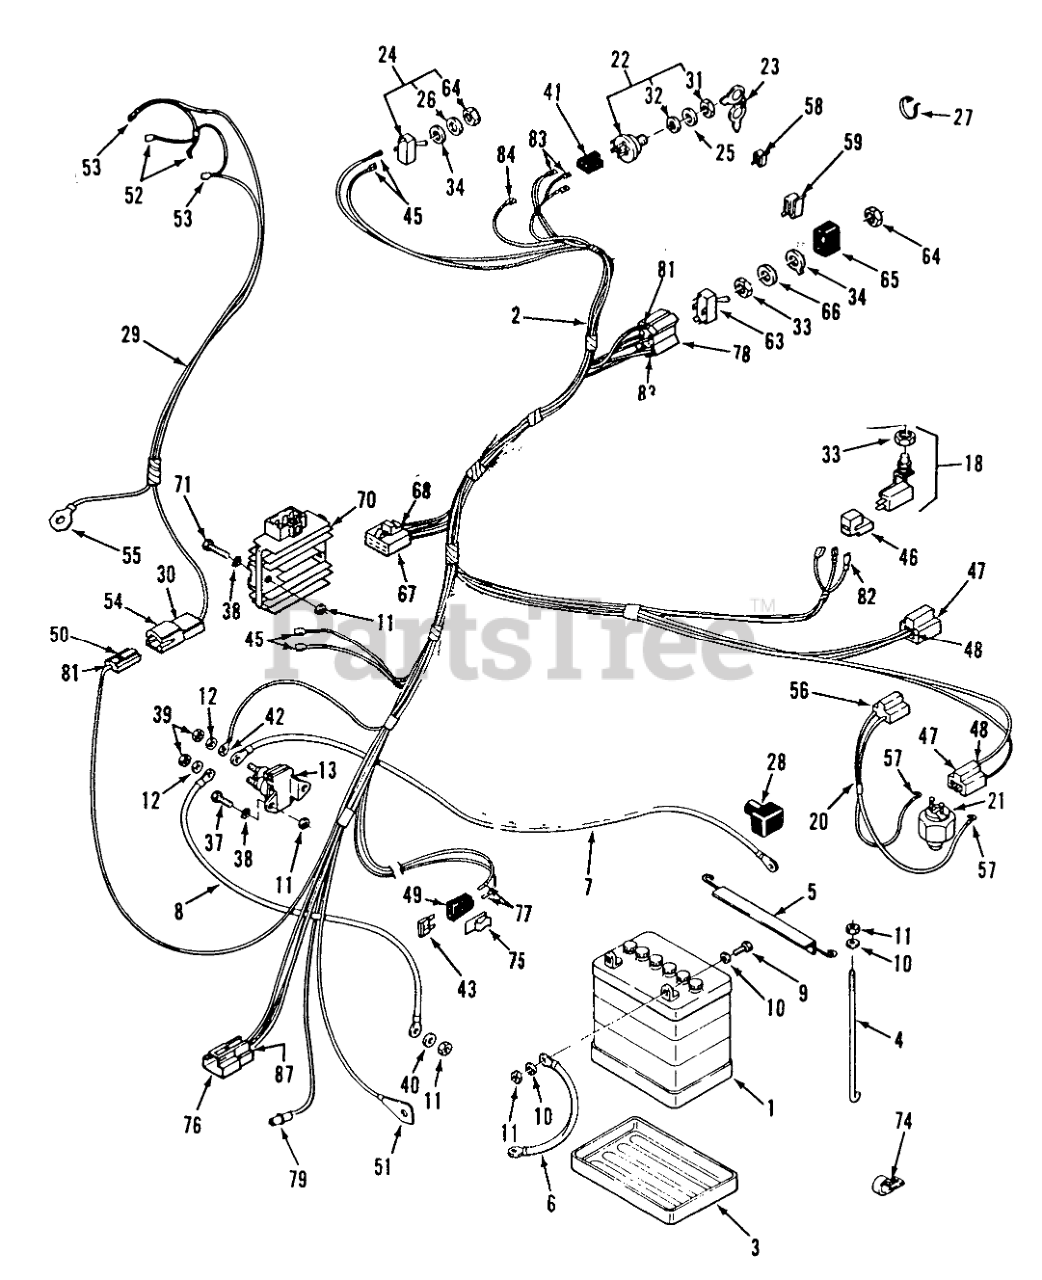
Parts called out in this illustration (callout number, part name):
1	Battery
2	MAIN HARN & WIR DIAG
3	TRAY BATTERY
5	HOLDDOWN-BATTERY
6	WIRE -BLACK
7	WIRE - 14" BLACK
8	ASSY WIRE
9	Bolt
11	Nut
12	Washer
13	Solenoid (Includes two of item 11) 210-4
18	Seat Switch
20	ASSY WIRING HARNESS
21	SWITCH (N.C.-TRANS)
22	Ignition Switch (Includes Items 31 & 32)
23	Ignition Key
24	Light Switch (includes items 33 & 34)
25	Washer
26	Washer
27	PLASTIC TIE
28	Boot
29	Headlight Harness 212
32	LOCKWASHER
33	NUT-HEX, SPECIAL
34	TAB-WASHER
37	HHCS 1/4-20X1" WHIZ
38	LOCKWASHER
39	Nut
40	Washer
41	CONNECTOR-5 WAY-SERV
42	Ring Terminal (part of item 2)
43	FUSE-BLADE, 15 AMP
45	Connector .250 x .032
46	CONNECTOR BODY
47	CONNECTOR BODY
48	TERMINAL-LONG MALE
49	FUSE-BLOCK ASS'Y
50	CONNECTOR BODY ELECT
51	Ring Terminal
52	Male Terminals (Part of 1)
53	Female Dbl. Crimp Terminal (part of item 29) 211
54	Connector Part of 5
55	Ring Terminal (part of item 2)
56	CONNECTOR BODY B
57	TERMINAL-TAB RCPT
58	CLIP
59	SPEED CLIP
63	Electric Clutch Switch (includes items 33, 34 & 64)
65	COVER-PTO SWITCH
66	WASHER
67	CONNECTOR BODY
70	REGULATOR VOLTAGE
71	HHCS 1/4-20X1" WHIZ
74	CLAMP
76	3-CONTACT LOCK-TYPE
77	Fuse Holder Term. (1 used on 212) 208, 211
78	CONNECTOR 5 WAY
79	Connector-Socket
81	Wire Terminal (Part of 1)
82	Wire Terminal (Part of 1)
83	Male Terminals (Part of 1)
84	Belt Guide-Bottom 308 Only
87	Long Male Terminal .248 x .032
